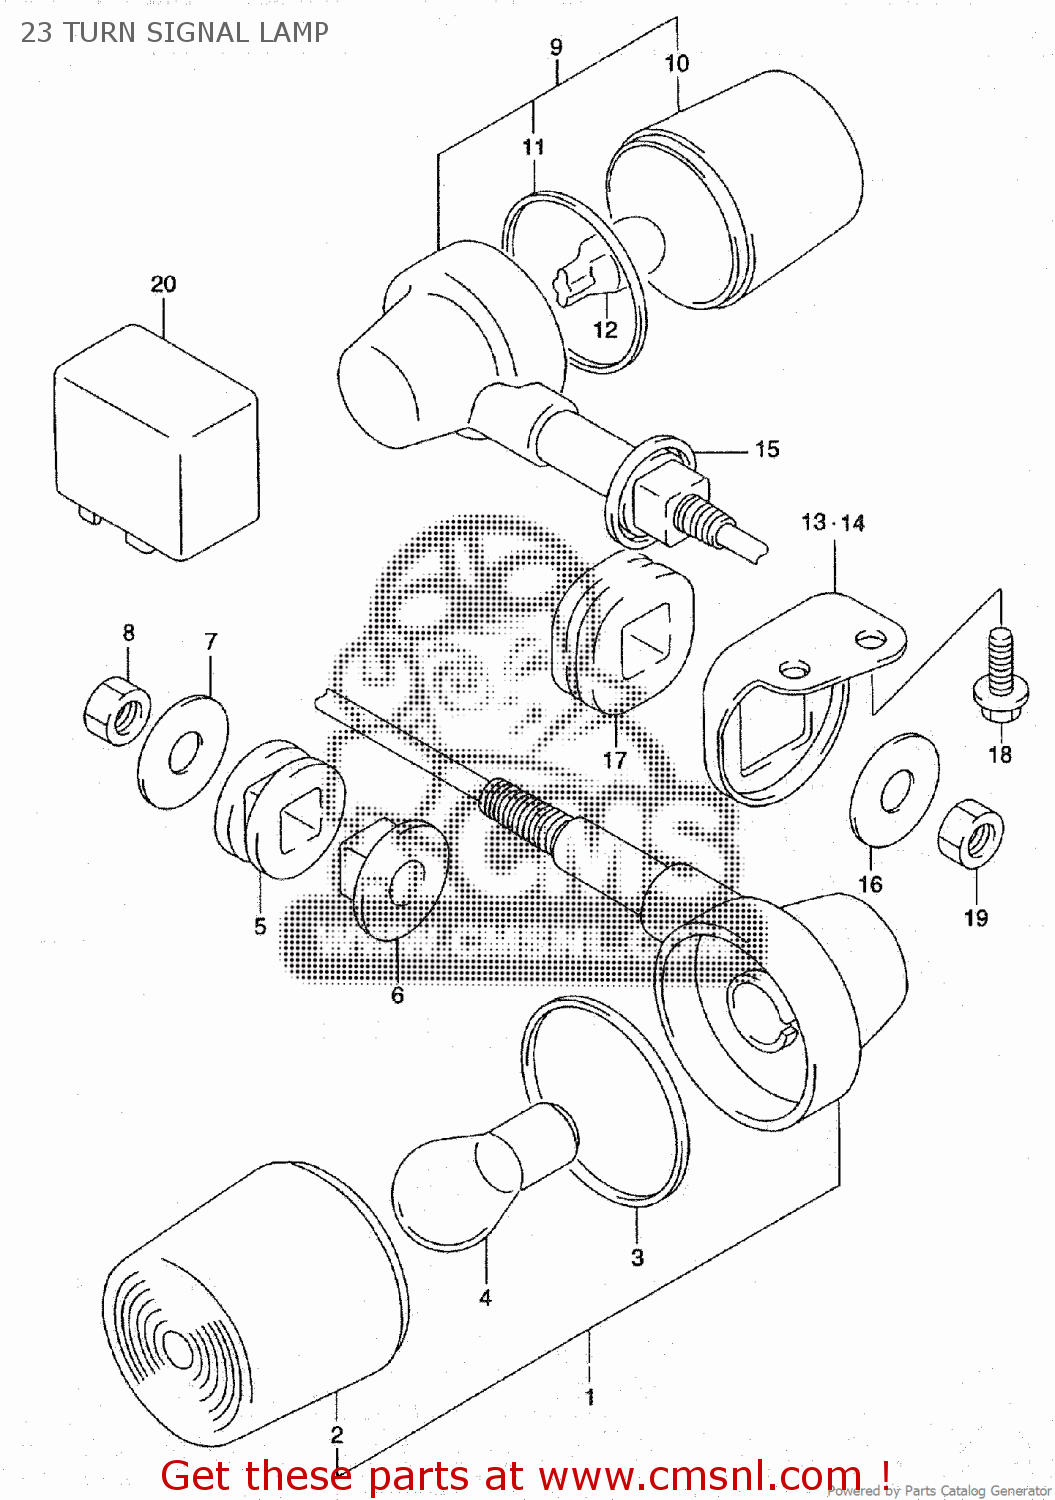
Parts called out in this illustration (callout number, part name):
1	LAMP ASSY,FR TURN SIGNAL,R
4	BULB(12V18/5W)
5	CUSHION
7	WASHER(10.5X30X2.3)
8	NUT
12	BULB(12V16W,W16W)
16	WASHER(10.5X30X2.3)
17	CUSHION
18	BOLT
19	NUT
20	RELAY ASSY,TURNSIGNAL
